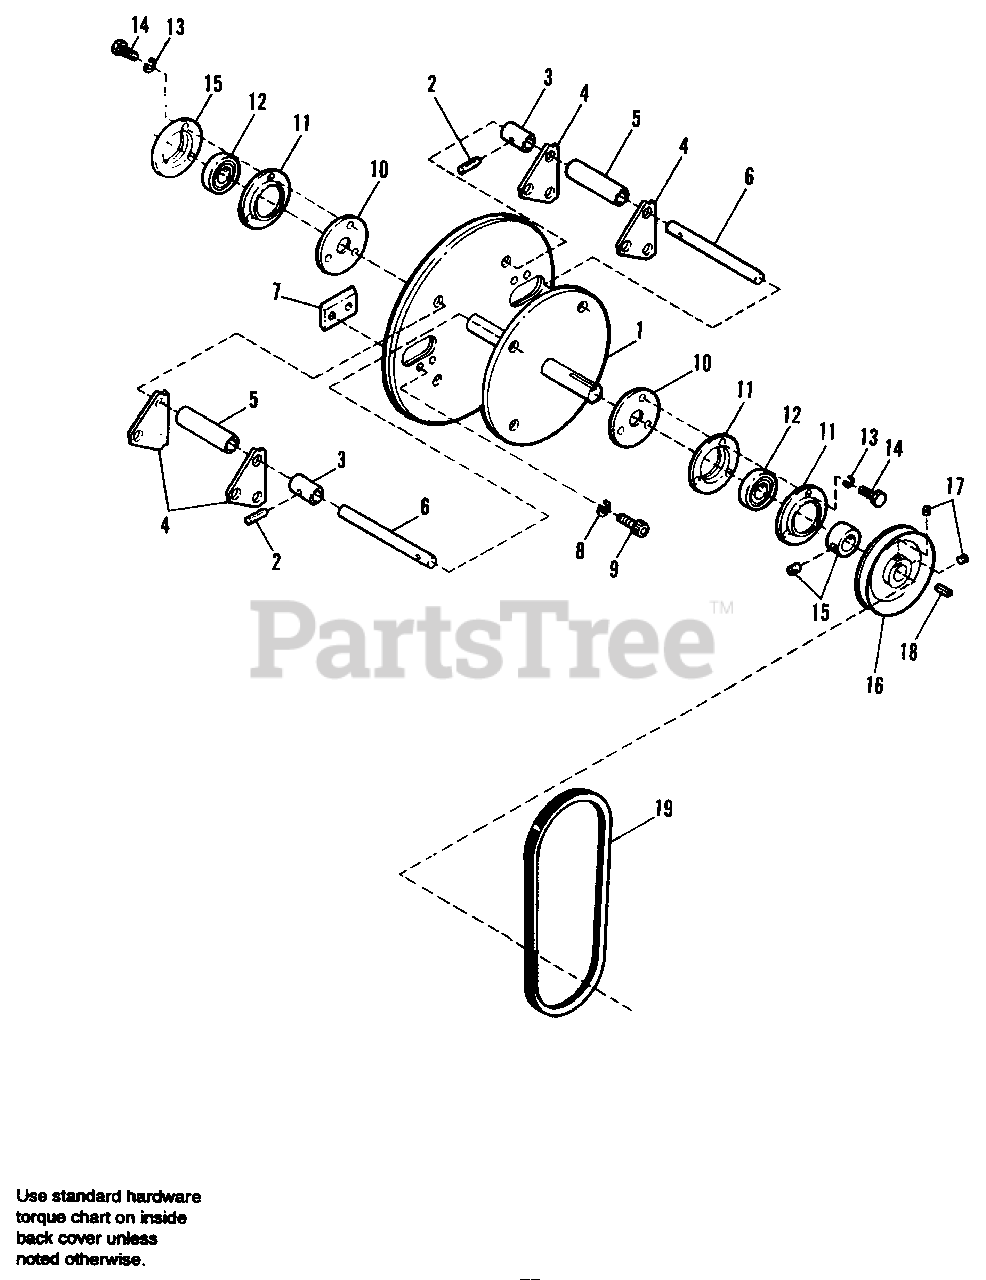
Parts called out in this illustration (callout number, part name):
2	ROLL PIN, 3/16 x 3/4
3	SPACER, Short
5	SPACER, Long
8	LOCKWASHER, Internal Tooth, 5/16,
9	CAPSCREW, Socket Head, 5/16-24 x 5/8
10	BEARING GUARD
12	BEARING, Cartridge
13	LOCKWASHER, Split, 5/16
14	CAPSCREW, Hex, 5/16-18 x 3/4
15	FLANGETTE, w/Zerk Fitting
17	SCREW, Set, 5/16-18 x 1/4
18	KEY, Sq., 1/4 x 1-1/4
